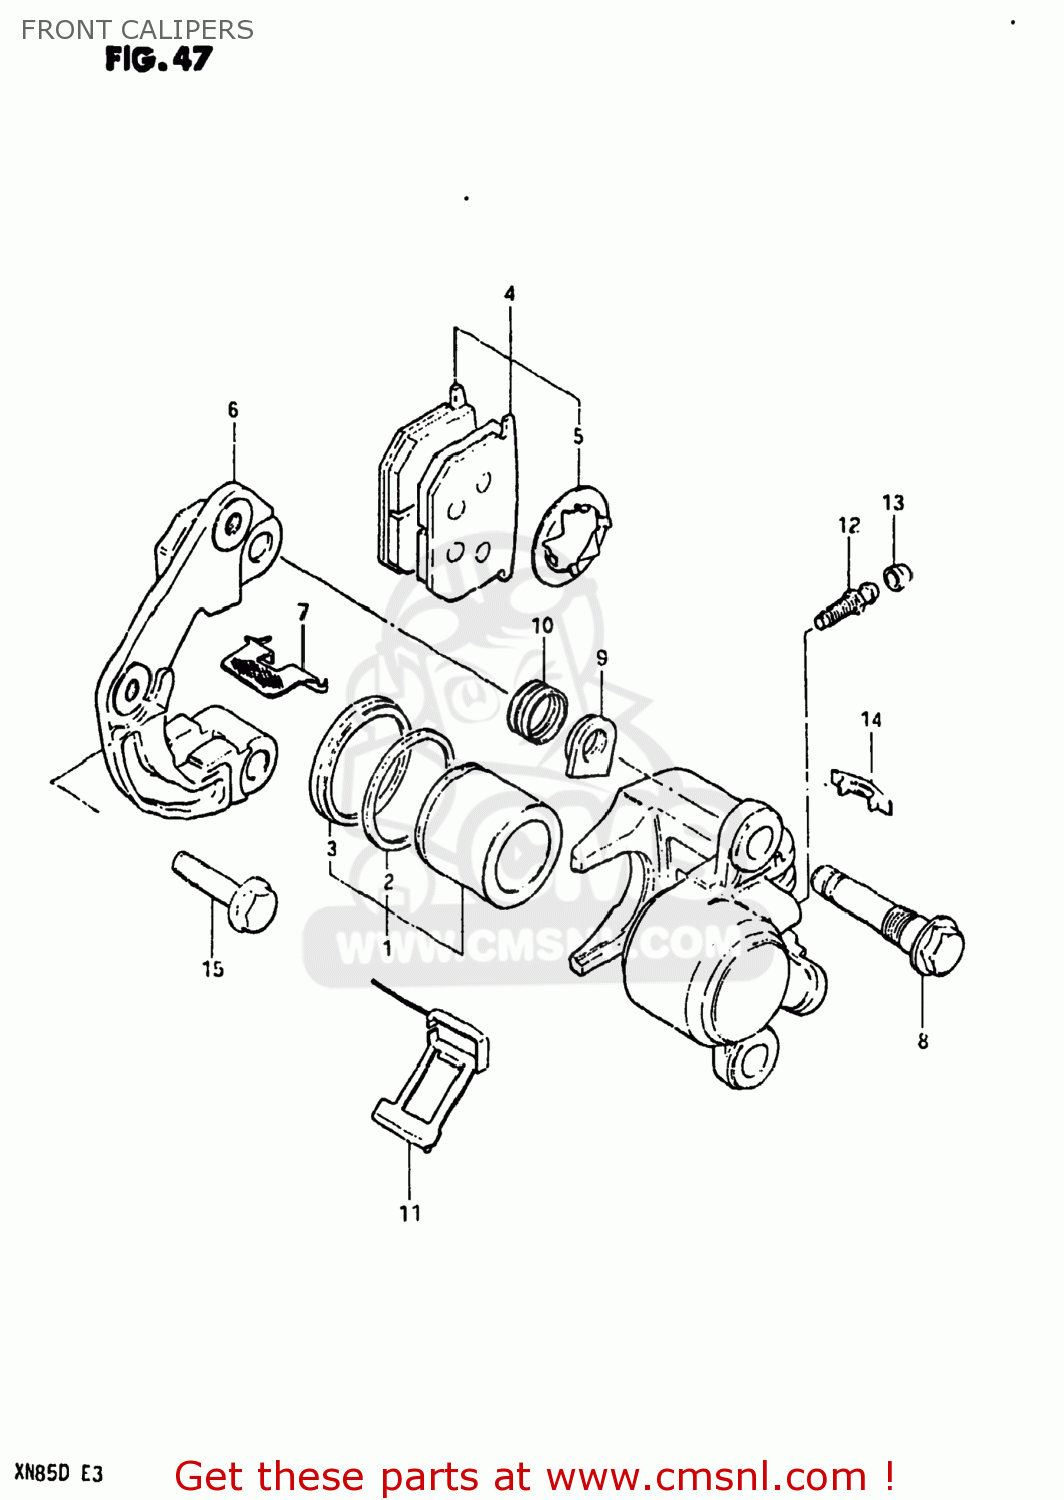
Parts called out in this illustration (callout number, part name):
0	CALIPER ASSEMBLY,LEFT
1	PISTON SET
2	SEAL,PISTON
3	BOOT,PISTON
4	PAD & SHIM SET (MCA)
5	SHIM,PAD
6	HOLDER,CALIPER,LEFT
7	PAD,GUIDE
8	AXLE
9	NUT,CALIPER AXLE
10	BOOT
11	SPRING
12	BREATHER
13	CAP,BLEEDER PL
14	COVER,INDICATOR
15	BOLT
